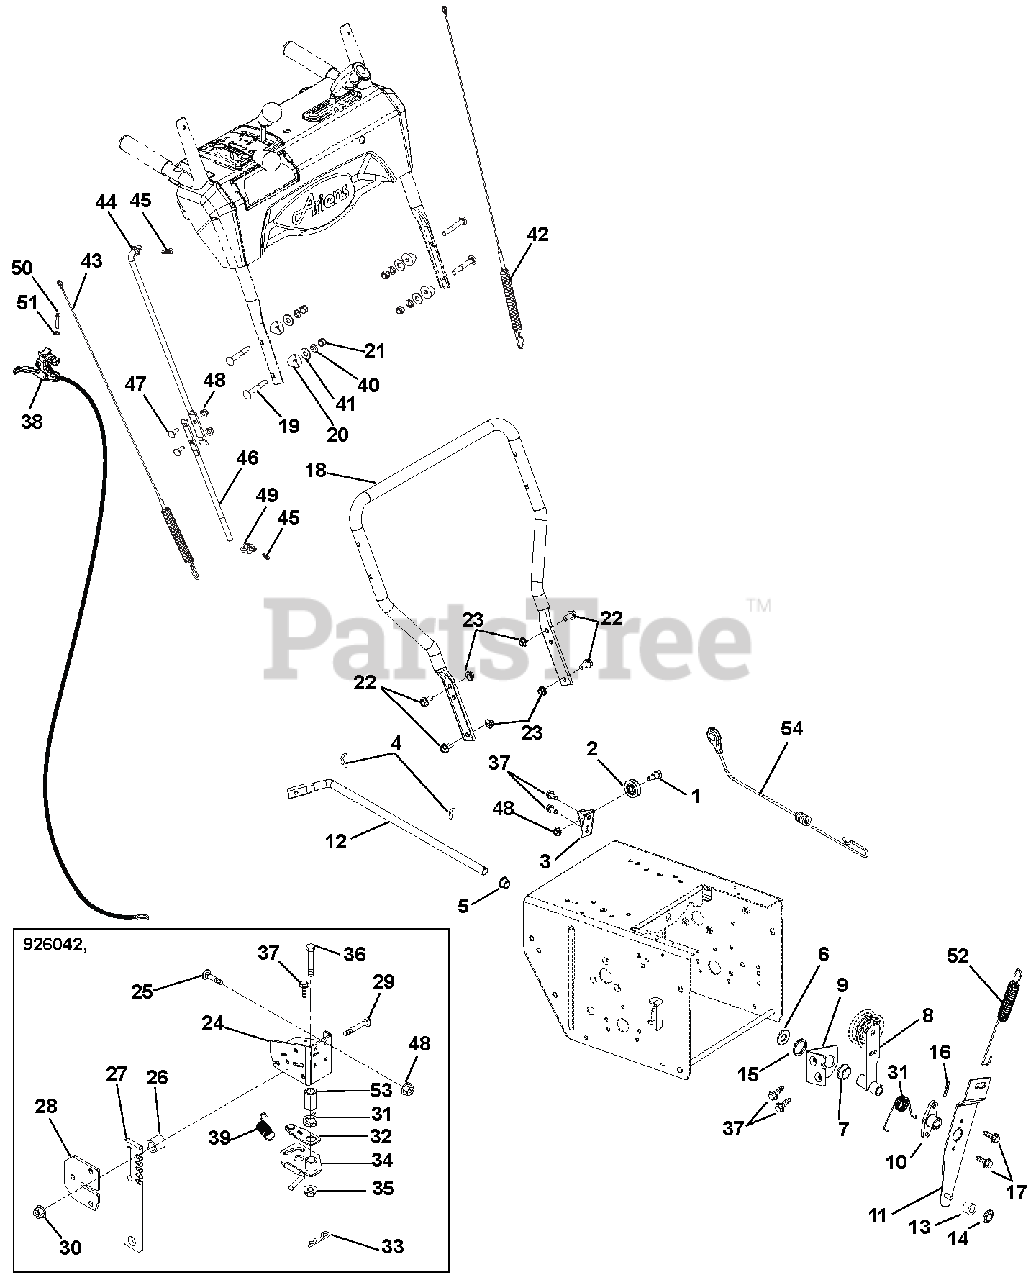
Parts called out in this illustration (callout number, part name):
1	BOLT, SHLDR-.375X.375X.25-20
2	PULLEY, CABLE
3	BRACKET, CABLE PULLEY
4	CLIP, SPRING
5	BUSHING, POLYLINER-.50 SPLIT
6	@WSHR-FL-STL.531X1.06X.095YWZC
7	BUSHING, POLYLINER-.50 SNAPIN
7	BSHG,FLANGE .500X.625X.270X.75
8	ARM, IDLER-TRACTION
9	BRACKET, SUPPORT
10	HUB, BRAKE ARM
11	ARM, IDLER-ATTACHMENT
12	ARM, ATTACHMENT
13	BSHG,SLV .265 X .625 X .375
14	RG-RTNG-EXT .250X.010
15	WAVE WASHER .531X.781X.125FH
15	WAVE SPRING .600X.875X.25FH
16	PIN-ROLL .125X1.00
17	SCR-TAP .25-20X.75 HWH TR YWZ
18	HANDLEBAR, LOWER
19	@BLT-RDHDSQNK .31-18X2.25 G5YZ
20	SPACER, HANDLEBAR
21	@NUT-LK-NYL .312-18 YWZC
22	BLT-SERHFWH .38-16X.75 YWZC
23	@NUT-LK-TOP-FLG .38-16 YWZC
24	BRACKET, HEIGHT ADJUSTER-PRO
25	@BLT-RDHDSQNK .25-20X.75 G5YZ
26	SPACER .50 X .32 X .42
27	STOP, HEIGHT ADJUSTER-PRO
28	PLATE, HEIGHT ADJUSTER
29	@BLT-RHDSHSQNK.31-18X1.25 G5YZ
30	@NUT-LK-TOP-FLG .31-18 YWZC
31	SG-TORS .067X.88
32	ARM, OVERTRAVEL
33	PIN-HAIR INT .06X.18X.77
34	LOCK, HEIGHT ADJUSTER
35	NUT-LK-CTR-FLG .38-16 YWZC
36	@BLT-HEX .38-16X1.75 GR5 YWZC
37	SCR-TAP .25-20X.50 HWH TR YWZ
38	CABLE, TRACK REMOTE
39	SPRING-EXT .047 X .438 X 1.85
40	WSHR-LK .312X.097 HVY YWZC
41	@WSHR-FL-STL.38X.875X.083 YWZC
42	CABLE, UPPER TRACTION
43	CABLE, AUGER (DELUXE & PRO)
44	ROD, SHIFT - UPPER
45	PIN-HAIR INT .08X.18X1.18 YWZC
46	ROD, SHIFT - LOWER
47	@BLT-RDHDSQNK .25-20X.75 G5YZ
48	@NUT-LK-TOP-FLG .25-20 YWZC
49	PIVOT,SHIFT ROD .375-16(TRUNN)
50	SCR-MCH .25-20X1.50 OVAL HD
51	WSHR-LK-INT .250 TH TYA
52	SG-TENS .06X.482X5.35
53	BSHG-SLV .385X.500X1.045
54	CABLE, LOWER TRACTION,SS & PRO
